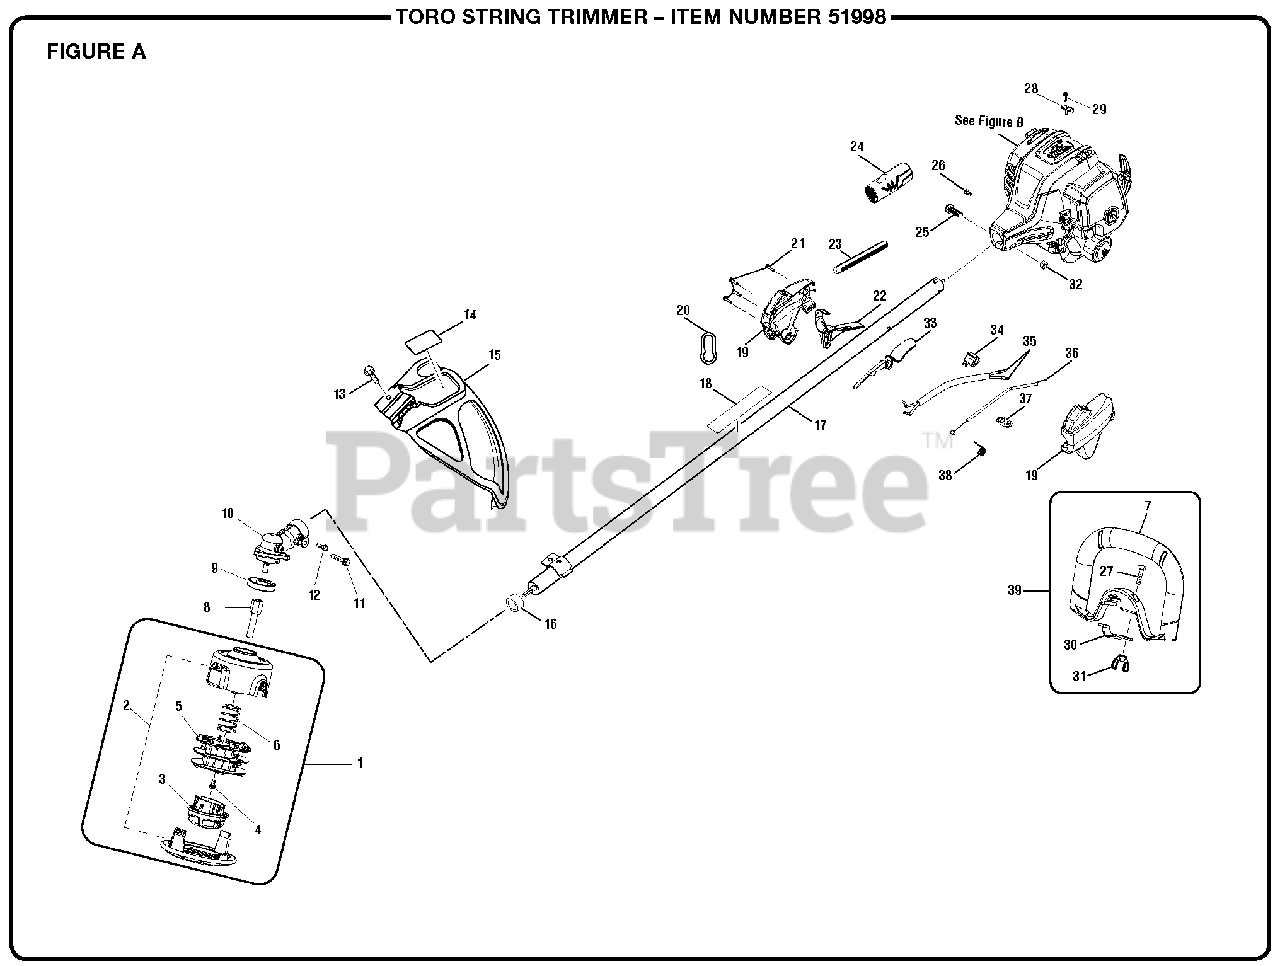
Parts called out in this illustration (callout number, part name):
1	Trimmer Head Assembly
2	Stringhead Housing
3	Bump Knob
4	Bolt (5/16-18 x 1/2 in., L.H.)
5	Spool Assembly
6	Compression Spring
7	Front Handle w/Grip
8	Trimmer Head Shaft Adaptor
9	Flanged Washer
10	Gear Case Assembly
11	Screw (1/4-20 x 1-1/4 in., Hex Washer Hd. S.T.)
12	Screw (10-24 x 5/8 in., Hex Washer Hd. S.T.)
13	Screw (1/4-20 x 1-1/4 in., Hex Washer Hd.)
14	Grass Deflector Label
15	Grass Deflector Assembly
17	Upper Boom Assembly
18	Warning Label
19	Control Handle Assembly
20	Shoulder Strap Clip
21	Screw (M4 x 20 mm, T20 Torx Pan Hd. S.T.)
23	Corrugated Tube (225 mm)
24	Rear Handle Grip
25	Screw (M6 x 30 mm, T27 Torx Button Hd.)
26	Screw (M4 x 8 mm, T20 Torx Pan Hd. S.T.)
27	Screw (1/4-20 x 1 in., Sq. Hd.)
28	Throttle Cable Clamp
29	Screw (M4 x 16 mm, T20 Torx Pan Hd. S.T.)
30	Front Handle Clamp
31	Wing Nut (1/4-20)
32	Hex Nut (M6 x 1)
33	Trigger Lock
34	On/Stop Switch
36	Throttle Cable
37	On/Stop Label
38	Trigger Spring
39	Front Handle Assembly
